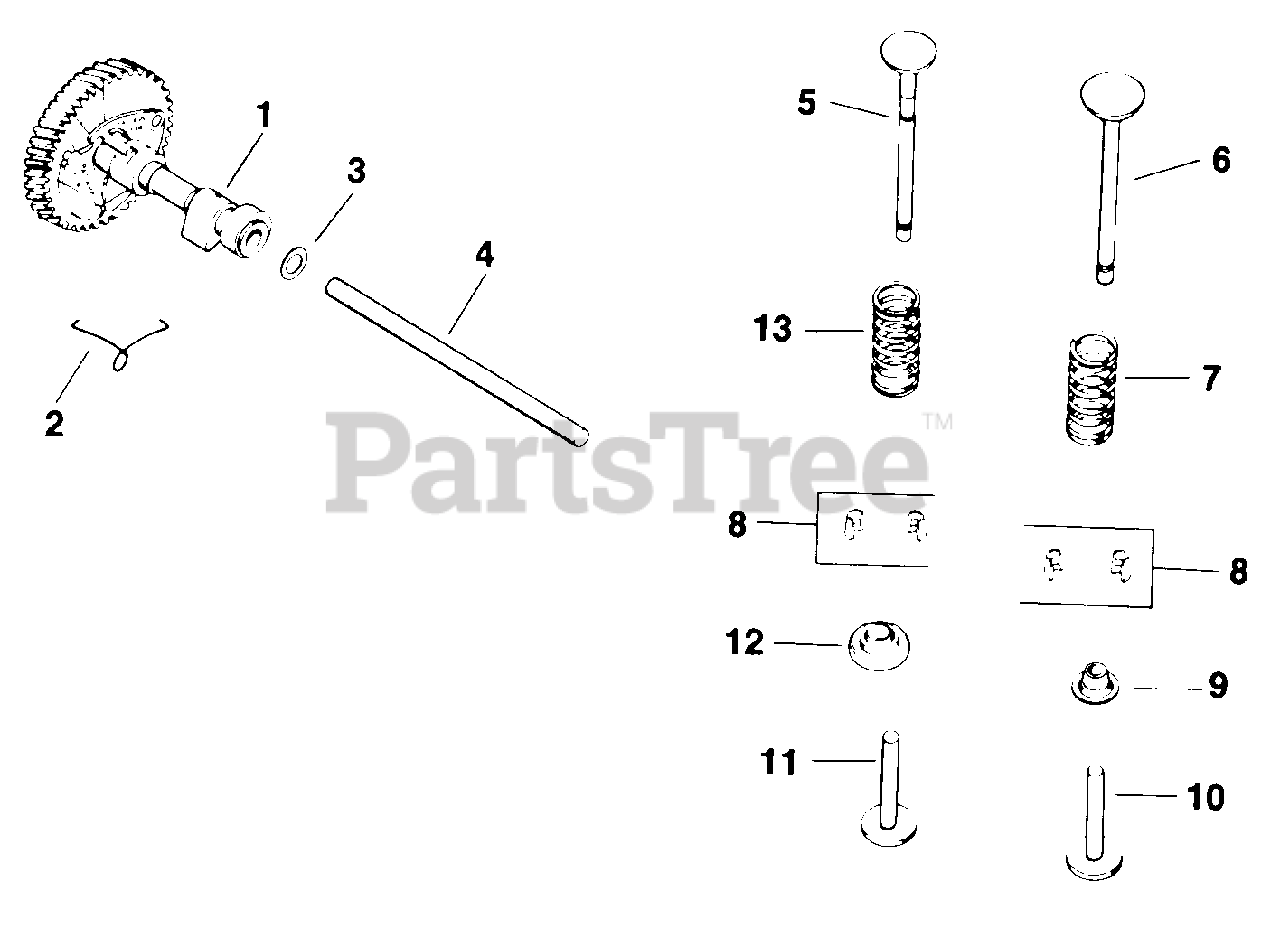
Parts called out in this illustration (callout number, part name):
2	Spring, Actuating
3	Spacer Camshaft .005
4	Pin, Camshaft
5	Valve, Exhaust
6	Valve, Intake
7	Spring, Intake Valve
8	Kit, Retainer
9	Retainer, Intake Spring
10	Tappet, Intake Valve
11	Tappet Exhaust Valve
12	Rotator, Valve
13	Spring, Exhaust Valve
